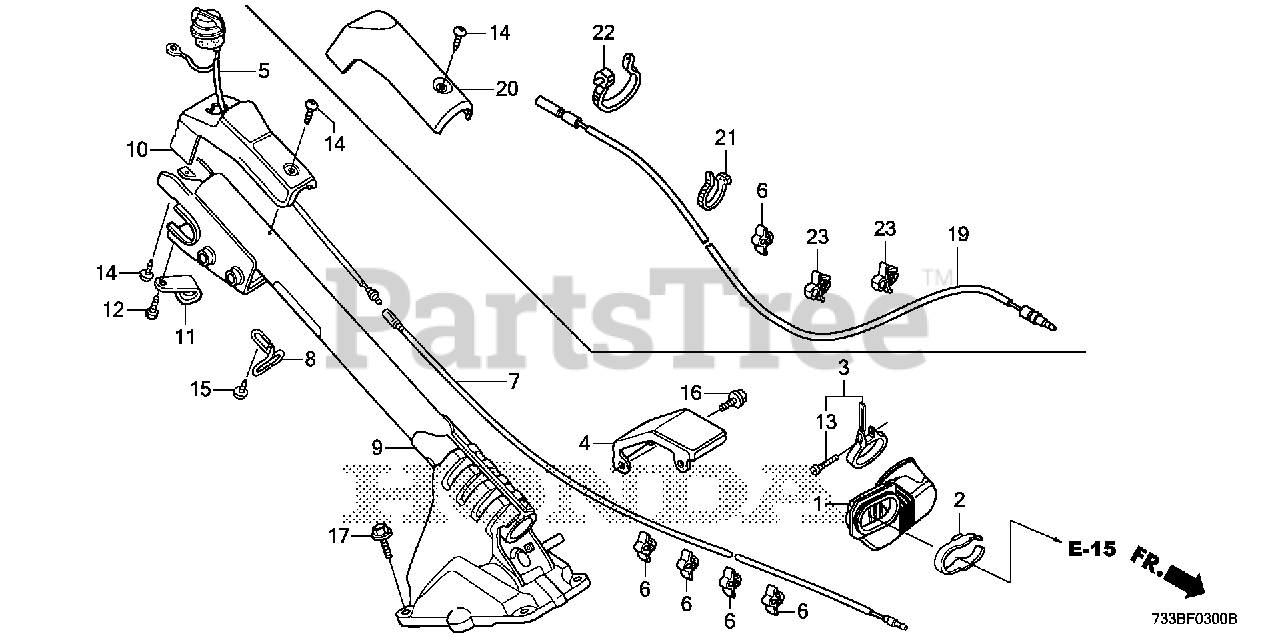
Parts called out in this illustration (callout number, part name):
1	HOSE, AIR CLEANER
2	CLIP, AIR CLEANER HOSE
3	BAND ASSY., AIR CLEANER HOSE
4	COVER, CHANGE
5	SWITCH ASSY., ENGINE STOP
6	HOLDER, STOP SWITCH WIRE Use up to Engine SN 2056819.
7	WIRE, ENGINE STOP
8	GUIDE, CABLE
9	COLUMN, HANDLE *R280* (POWER RED)
10	COVER, HANDLE COLUMN
11	CLIP, WIRE HARNESS (6.3MM)
12	BOLT, HEX. (5X14)
13	SCREW, PAN (4X30)
14	SCREW, TAPPING (5X12)
15	SCREW, TAPPING (5X10)
16	BOLT, FLANGE (6X10)
17	BOLT, FLANGE (8X16) Use from Engine SN 1000016.
